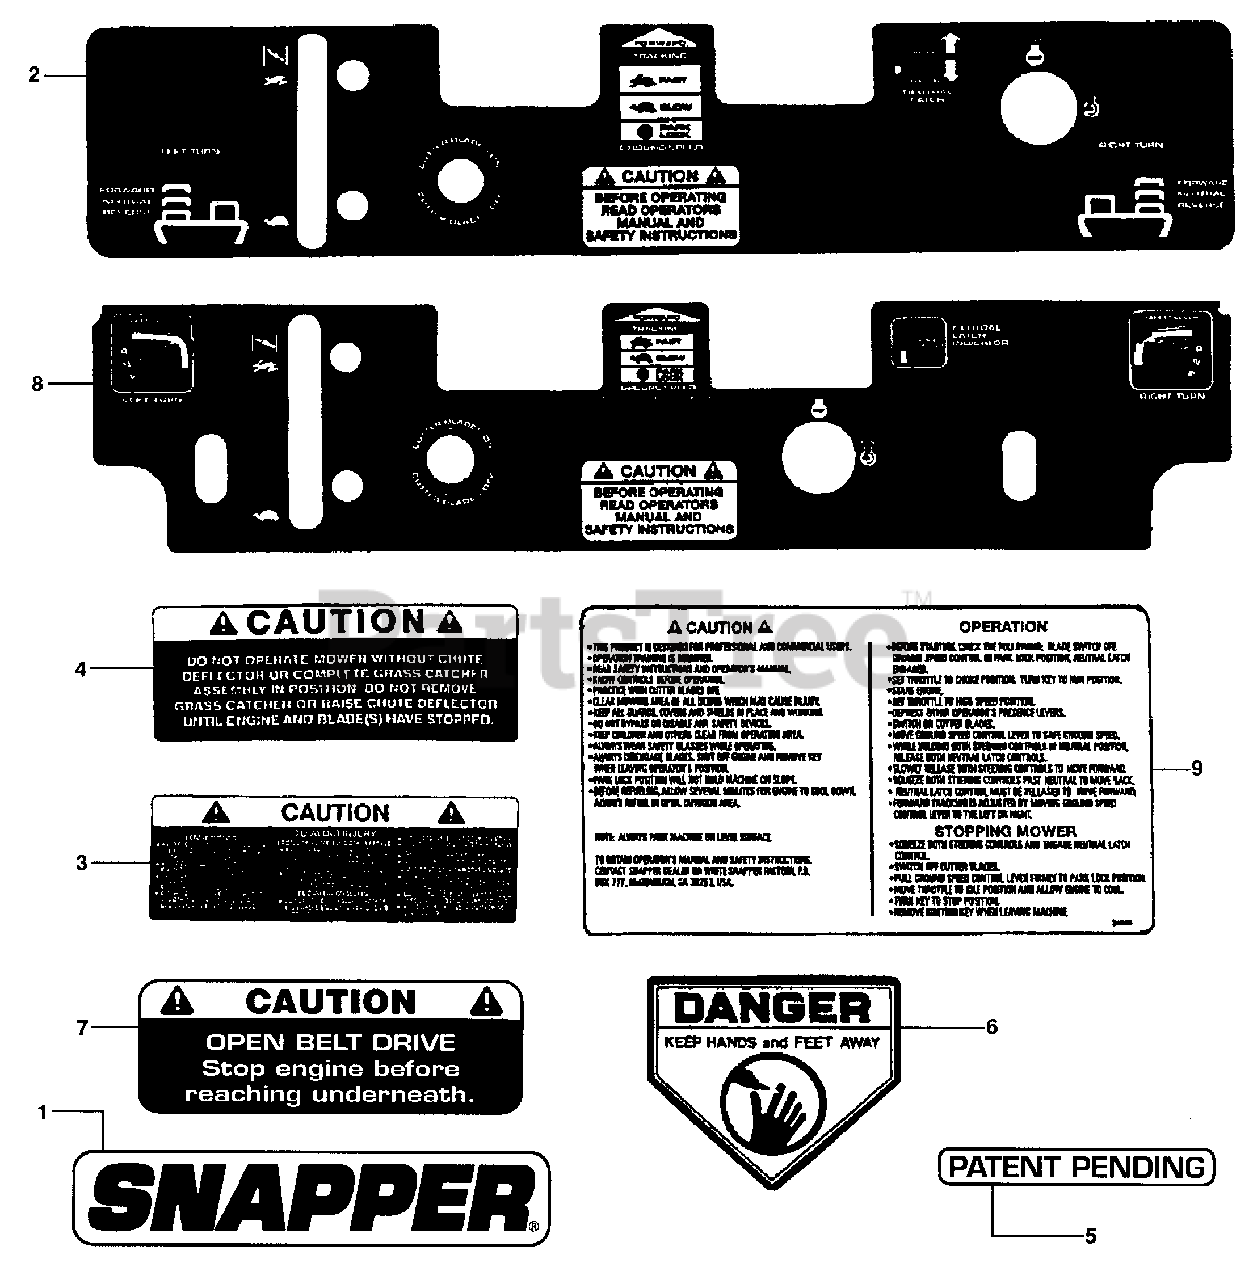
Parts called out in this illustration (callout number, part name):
1	DECAL, SNAPPER
2	DECAL, Console
3	DECAL, Caution
4	DECAL, Caution
5	DECAL, Patent Pending
6	DECAL, Warning
7	DECAL, Caution
8	DECAL, Console
9	DECAL, Caution (Hydraulic Oil Tank)
